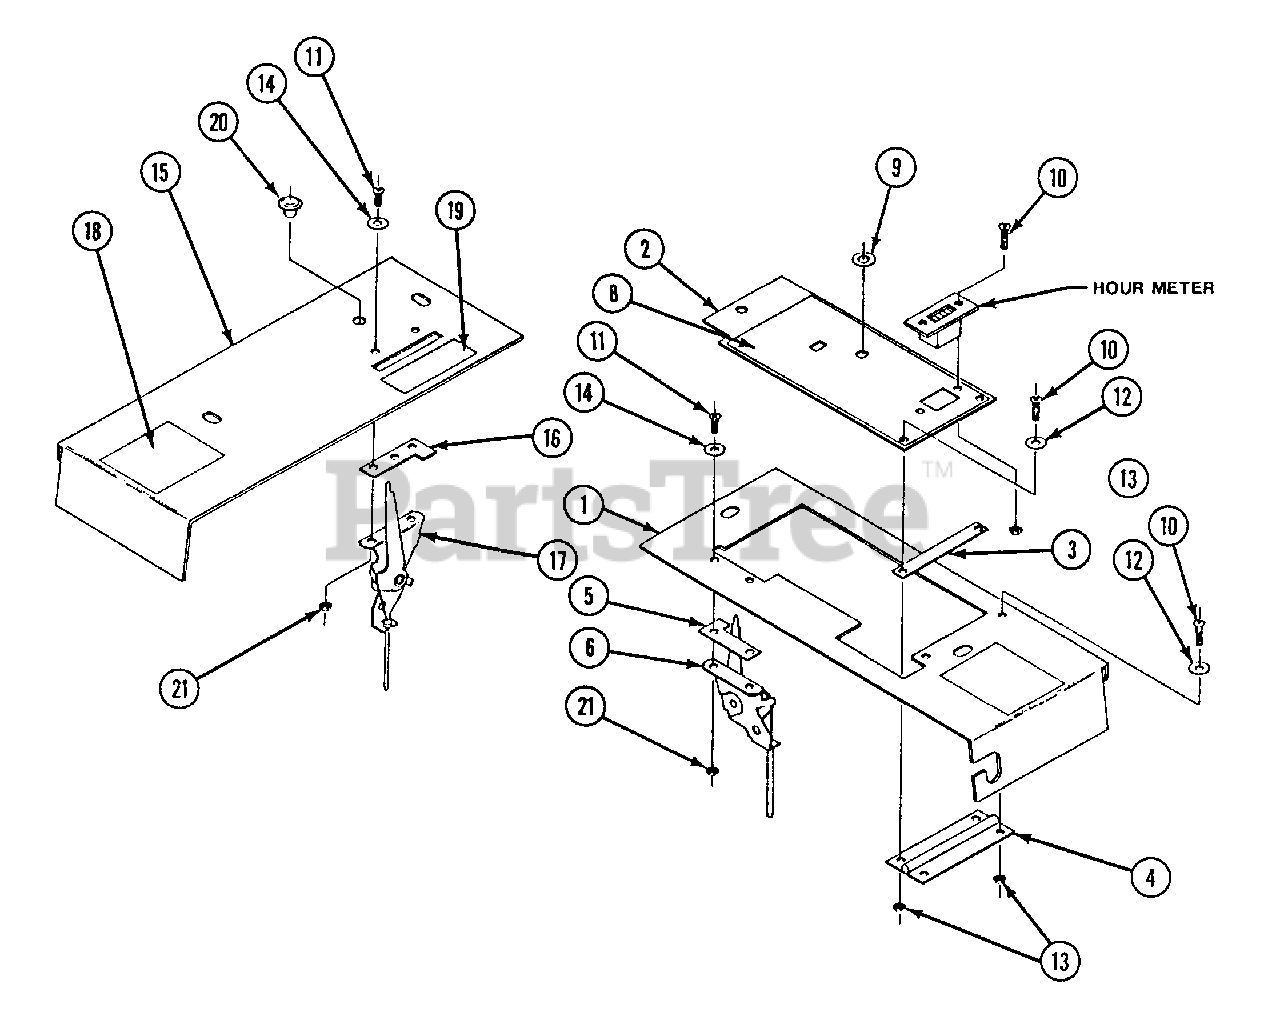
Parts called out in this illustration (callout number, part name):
1	FENDER CAP, RH (ORANGE)
2	INSTRUMENT PANEL (ORANGE)
3	HINGE SHIM
4	HINGE
5	THROTTLE STOP PLATE
6	THROTTLE CABLE
8	DECAL, INST. PANEL
9	D-WASHER FOR CLUTCH SWITCH
10	SCREW, MACHINE: 8-32 X 3/4
11	SCREW, MACHINE: 6-32 X 5/8
12	FLAT WASHER:
13	LOCKNUT, NYLOCK: 8-32
14	FLAT WASHER:NO.6
15	FENDER CAP, LH (ORANGE)
16	CHOKE STOP PLATE
17	CHOKE CABLE
18	DECAL,"CAUTION TO AVOID.."
19	DECAL,"CHOKE"
20	PLASTIC PLUG
21	LOCKNUT, NYLOCK: 6-32
